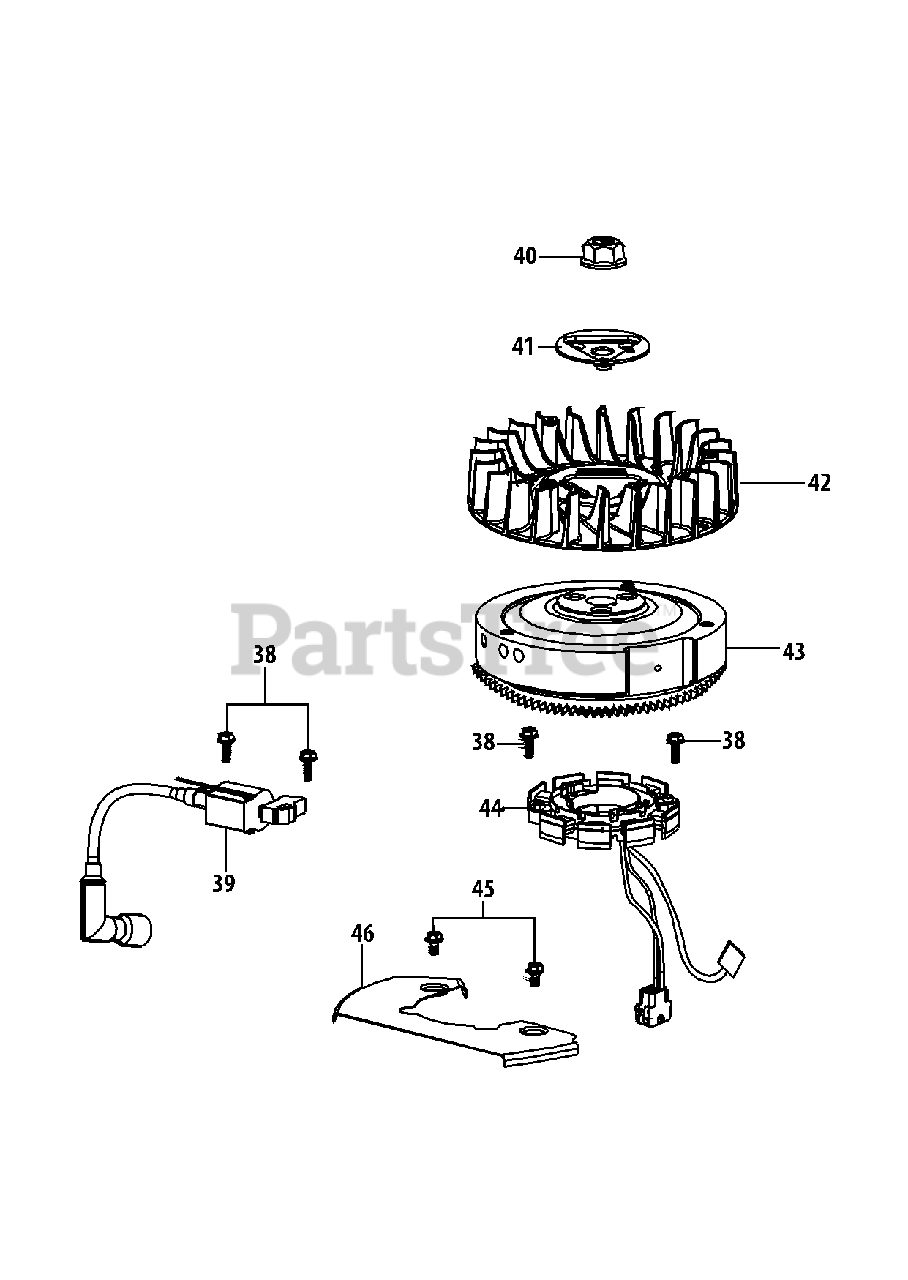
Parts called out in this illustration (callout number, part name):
38	Bolt M6×28
39	Ignition Coil Assembly
40	Flywheel Nut M16×1.5
42	Cooling Fan
43	Flywheel
44	Coil Assy.,Charge
45	Bolt M6×10
